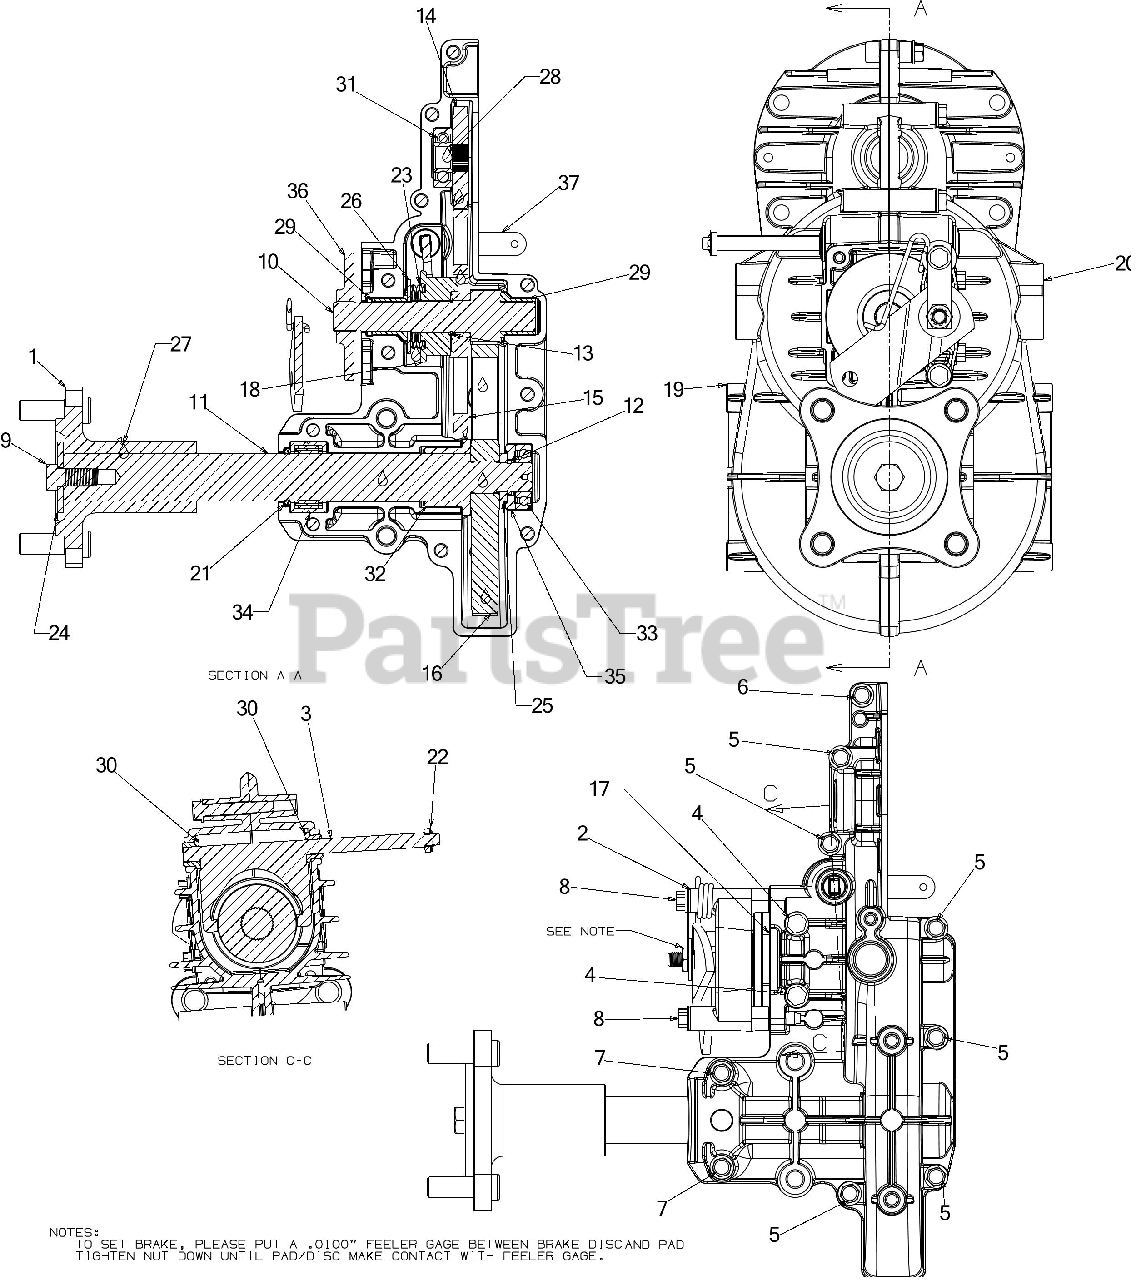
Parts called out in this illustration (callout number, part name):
1	WHEEL HUB ASSEMBLY
2	RIGHT HAND BRAKE
3	NEUTRAL DROP ACTUATOR
4	SCREW 1/4-20 x 2
5	SCREW 1/4-20 x 1.50"
6	SCREW 1/4-20 x 1.00
7	SCREW 1/4-20 x 1.25
8	SCREW 1/4-20 x 2.375
9	SCREW 3/8-16 x .75 GR 5
10	OUTPUT SHAFT 11T
11	AXLE SHAFT
12	SNAP RING
13	RETAINING RING
14	SPUR GEAR:22T
15	SPUR GEAR:53T:INPUT
16	SPUR GEAR 61T
17	BRAKE PUCK
18	U-TURN CLUTCH COLLAR
19	AXLE HOUSING
20	AXLE HOUSING
21	AXLE SEAL 1.0X1.25X.125
22	PUSH NUT:1/4 x 17/32
23	SPRING-1.00 x 1.375 X.400
24	FLAT WASHER .390x1.500x.134
25	FLAT WASHER .632X1.00X.16
26	FLAT WASHER .635X1.585X.062 HDN
27	ANTI-SIEZE GREASE (NOT SERVICEABLE)
28	GREASE (NOT SERVICEABLE)
29	FLANGE BEARING
30	SLOTTED FLANGE BEARING
31	SEALED BALL BEARING
32	FLANGE BEARING
33	BALL BEARING
34	NEEDLE BEARING
36	BRAKE DISC
37	LEVER PLATE
